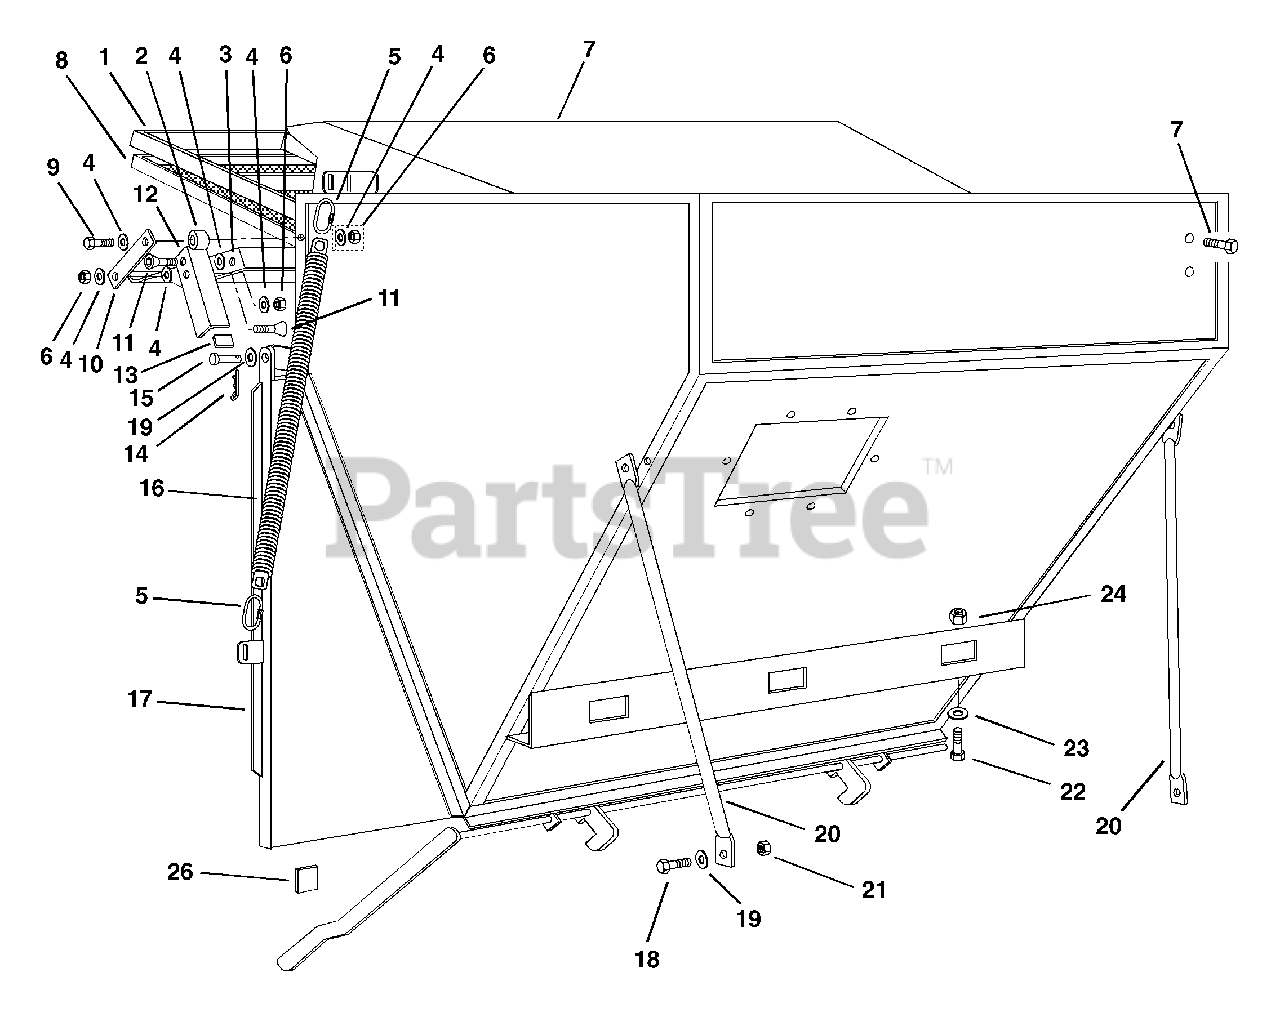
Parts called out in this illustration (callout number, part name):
1	Grid Weldment
2	Screen Door Link Spacer
3	Screen Door Weldment
4	Washer-Flat-Steel .38 x .975 x .083
5	1/4 inch Quick Link
6	Nut-Locking-Center .31-18
7	Hopper Weldment
8	Single Screen
9	Bolt-Hex .31-18 x 1.50 Grade 5
10	Filter Door Linkage
11	Screw-Machine .31-18 x 1.00
12	Filter Door Latch-Right Hand
12	Filter Door Latch-Left Hand
13	Gasket Material
14	Pin-Cotter .12 x .75
15	Clevis Pin
16	Spring
17	Door Weldment
18	Bolt-Hex .38-16 x 1.00 Grade 5
19	Washer-Flat-Steel .438 x 1.00 x .083
20	Hopper Brace
21	Nut-Locking-Center .38-16
22	Bolt-Hex .50-13 x 1.25 Grade 5
23	Washer-Flat-Steel .563 x 1.38 x .109
24	Nut-Locking-Center .50-13
25	Bolt-Hex .32-18 x .50 Grade 5
26	Gasket Material
